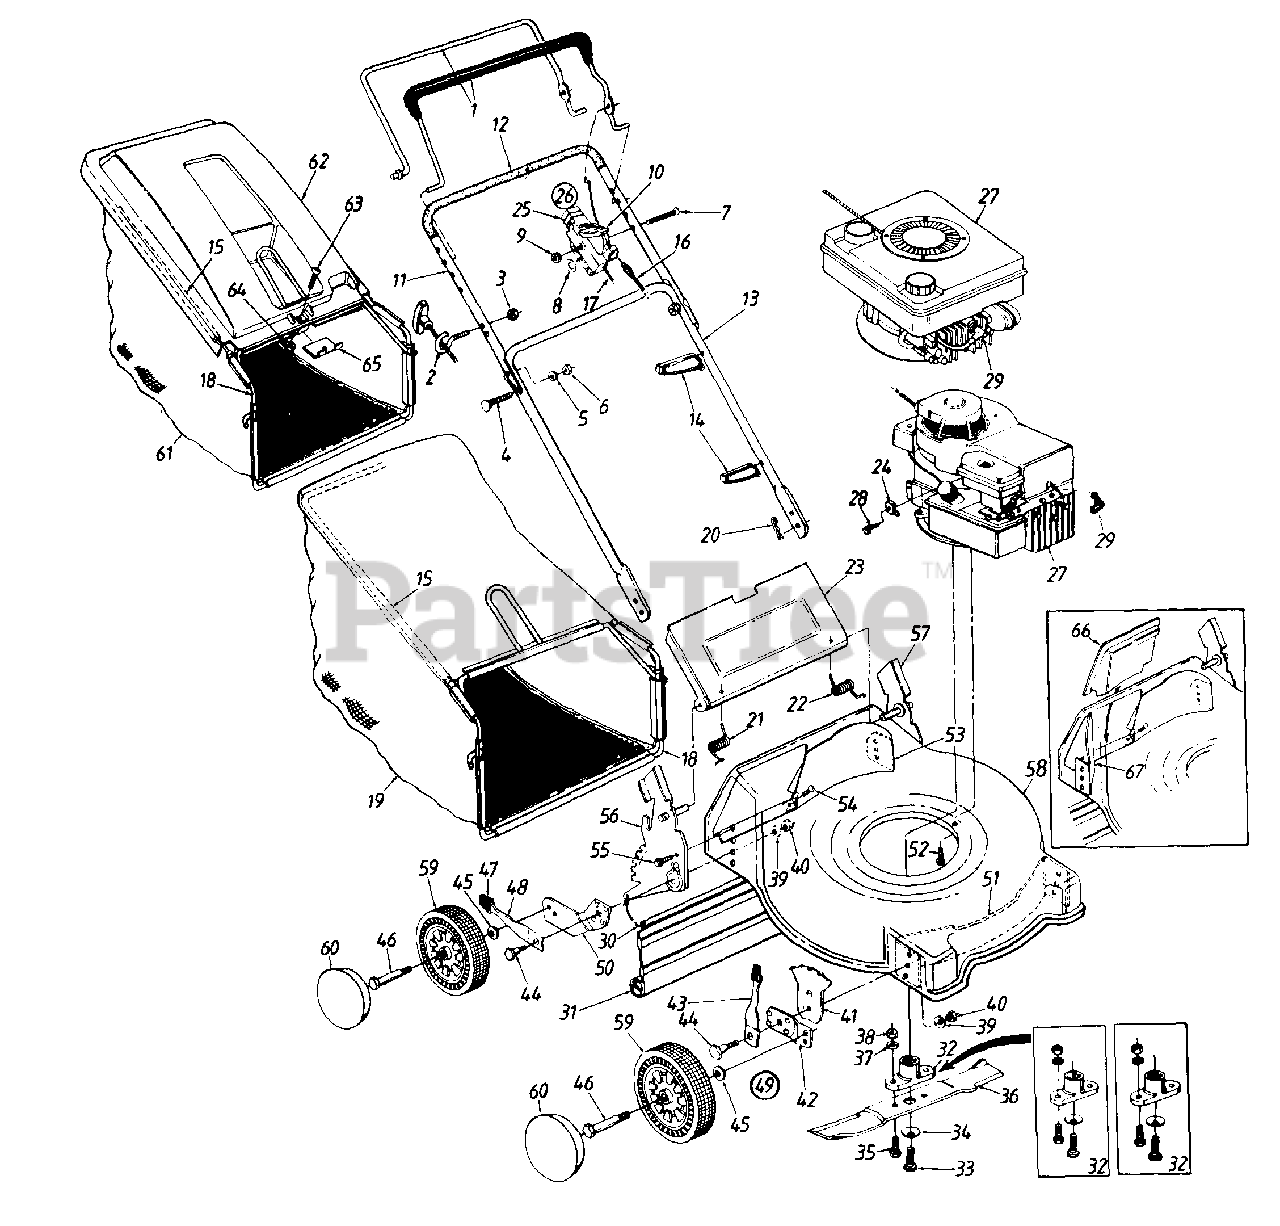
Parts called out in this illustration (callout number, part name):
2	Rope Guide Bolt
3	Hex L-Nut 1/4-20 Thd.
4	Curved Carr. Bolt 5/16-18 x 1.38" Lg.
5	L-Wash. 5/16" I.D.
6	Hex Nut 5/16-18 Thd.
7	Oval C-Sunk Mach. Scr.
8	Spr. Wash..66" I.D.
9	Hex L-Nut 1/4-20 Thd.
10	Throttle Lever
13	Lower Handle
14	Cable Tie
16	Control Cable - 39"
17	Throttle Control Wire - 51"
20	Int. Cotter Pin 5/16" Dia.
21	Door Spring - R.H.
22	Door Spring - L.H.
25	Throttle Body
26	Throttle Box Comp.
27	Engine
28	Hex Wash. Hd. Scr. #10-32 x .62" Lg. (B&S)
29	Spark Plug Boot
30	Wire Rod
31	Rear Flap
32	Blade Adapter Kit
33	Hex Bolt 3/8-24 x 1.5" Lg.
34	Bell-Wash..39" I.D.
35	Hex Bolt 3/8-24 x 1" Lg.
36	21" Blade
37	L-Wash. 3/8" I.D.
38	Hex Nut 3/8-24 Thd.
39	Bell-Wash..39" I.D. x 1.38"
40	Hex Nut 3/8-16 Thd.
41	Height Adj. Plate
43	Spring Lever Ass'y. w/Knob
44	Shld. Bolt .5" Dia. x .357"
45	Bell-Wash..38" I.D. x .88" O.D.
46	Axle Bolt
47	Spring Lever Knob
48	Spring Lever
49	Height Adj. Ass'y. Comp.- R.H.
50	Pivot Bar
54	Torx Mach. AB-Tap Scr. 1/4 x .62" Lg.
55	Hex L-Wash. Hd. AB-Tap Scr. 1/4 x .62" Lg.
56	Handle Brkt. Ass'y.- R.H.
57	Handle Brkt. Ass'y.- L.H.
60	Hub Cap
61	Grass Bag
62	Hard Top Cover
63	Pan Hd. Mach. Scr. 1/4-20 x .5" Lg.
64	Hex Nylon L-Nut 1/4-20 Thd.
